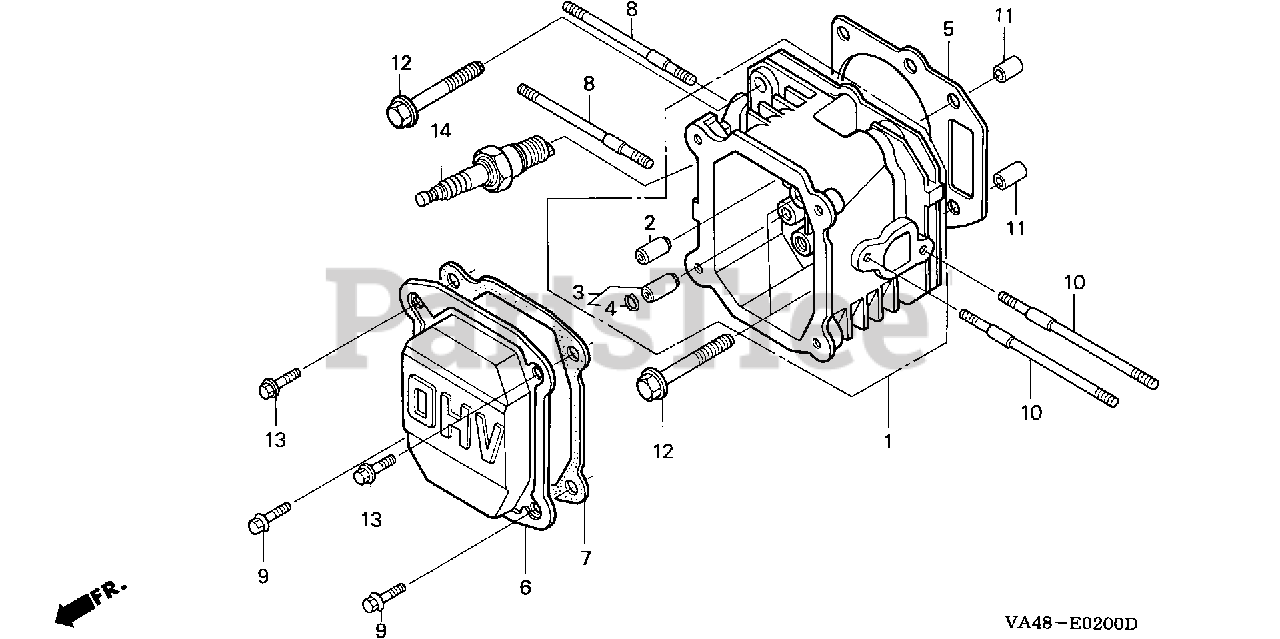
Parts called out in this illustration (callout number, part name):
1	CYLINDER HEAD
2	GUIDE, VALVE (OVER SIZE) Use from Engine SN 6324986.
3	GUIDE, EX. VALVE (OS)
4	CLIP, VALVE GUIDE Use from Engine SN 1231803.
5	GASKET, CYLINDER HEAD
6	COVER, HEAD
7	GASKET, CYLINDER HEAD COVER
8	BOLT, STUD (6X83)
9	BOLT, FLANGE (6X13)
10	BOLT, STUD (6X97)
11	PIN A, DOWEL (10X16)
12	BOLT, FLANGE (8X50)
13	BOLT, FLANGE (6X14)
14	SPARK PLUG (BPR4ES) (NGK)
14	SPARK PLUG (W14EPR-U) (DENSO)
14	SPARK PLUG (BP5ES) (NGK)
14	SPARK PLUG (W16EP-U) (DENSO)
14	SPARK PLUG (BP6ES) (NGK)
14	SPARK PLUG (W20EP-U) (DENSO)
